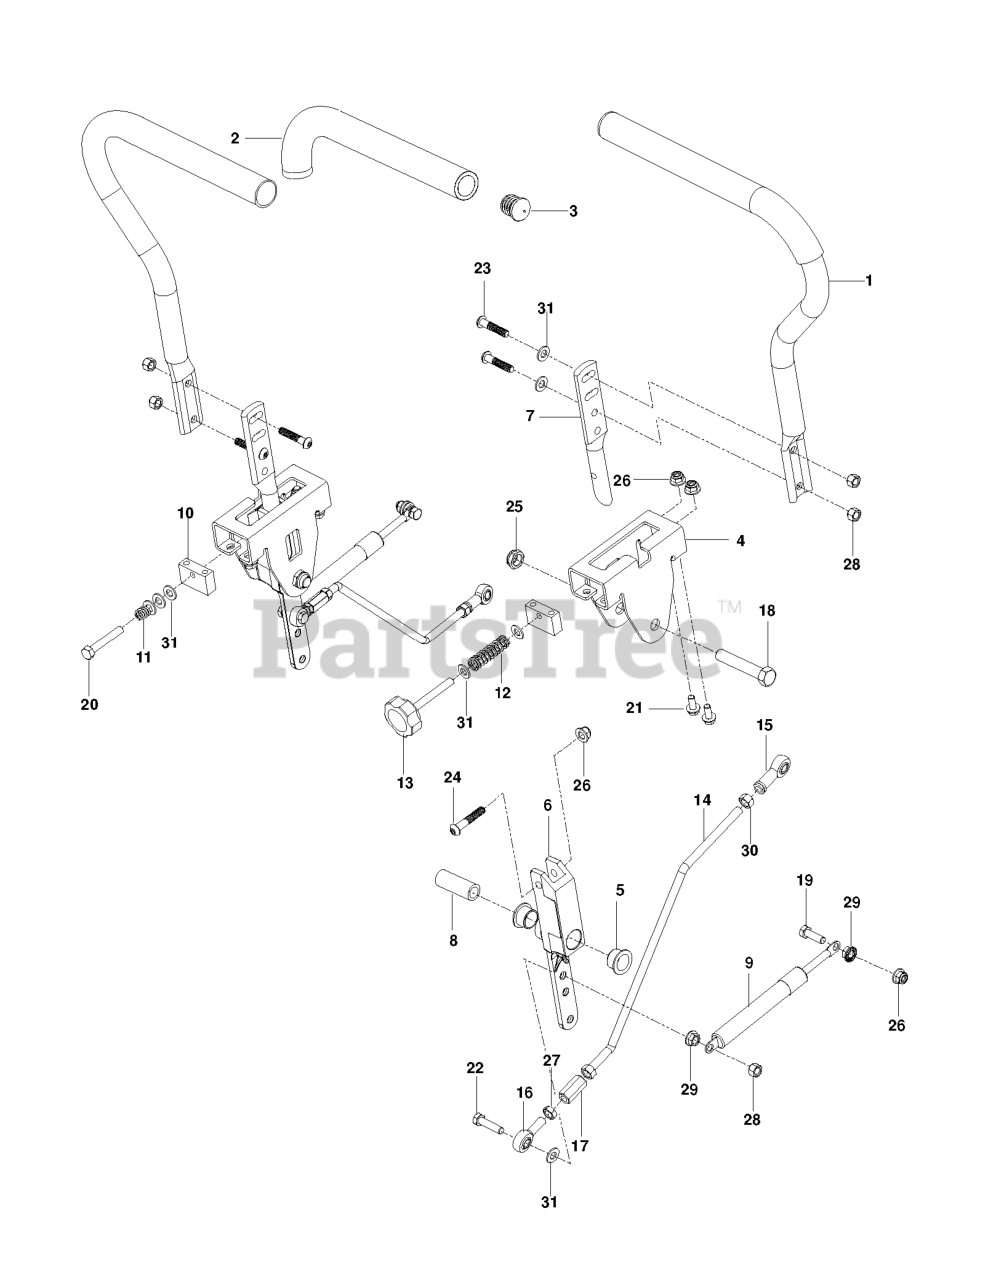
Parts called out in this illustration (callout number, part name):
1	LEVER ASSEMBLY
2	GRIP, FOAM (GROUND) 15
3	END PLUG 15/16 (BLACK)
4	BRACKET, CONTROL
5	BEARING, FLANGE
6	LEVER CONTROL PIVOT
7	LEVER.HANDLE MOUNT
8	SPACER, PIVOT CONTROL
10	BLOCK.TRACKING
12	SPRING COMPRESSION 2.0
13	KNOB
14	ROD, MOTION CONTROL
15	RH ROD END
16	RP.ROD.END.LH
17	ROD END COUPLER
18	HCS 1/2C X 2 3/4
19	HCS 5/16C X 1
20	CAPSCREW 5/16 X 1/1/2 HEX HEAD
21	HHFS 5/16-18 X 3/4
22	HCS 5/16C X 1 3/4
23	SCREW BUTTONHEAD 5/16-18X1-1/2
24	SCREW 5/16-18 X 1 3/4 BTN-HD
25	NUT 1/2-13 HEX JM NYL
26	5/16-18 NYLOC FLANGE NUT
27	NUT 5/16F LEFTHAND
28	NUT 5/16 NYLOC
29	NUT 5/16C WHIZ
31	FLAT WASHER 5/16 SAE
